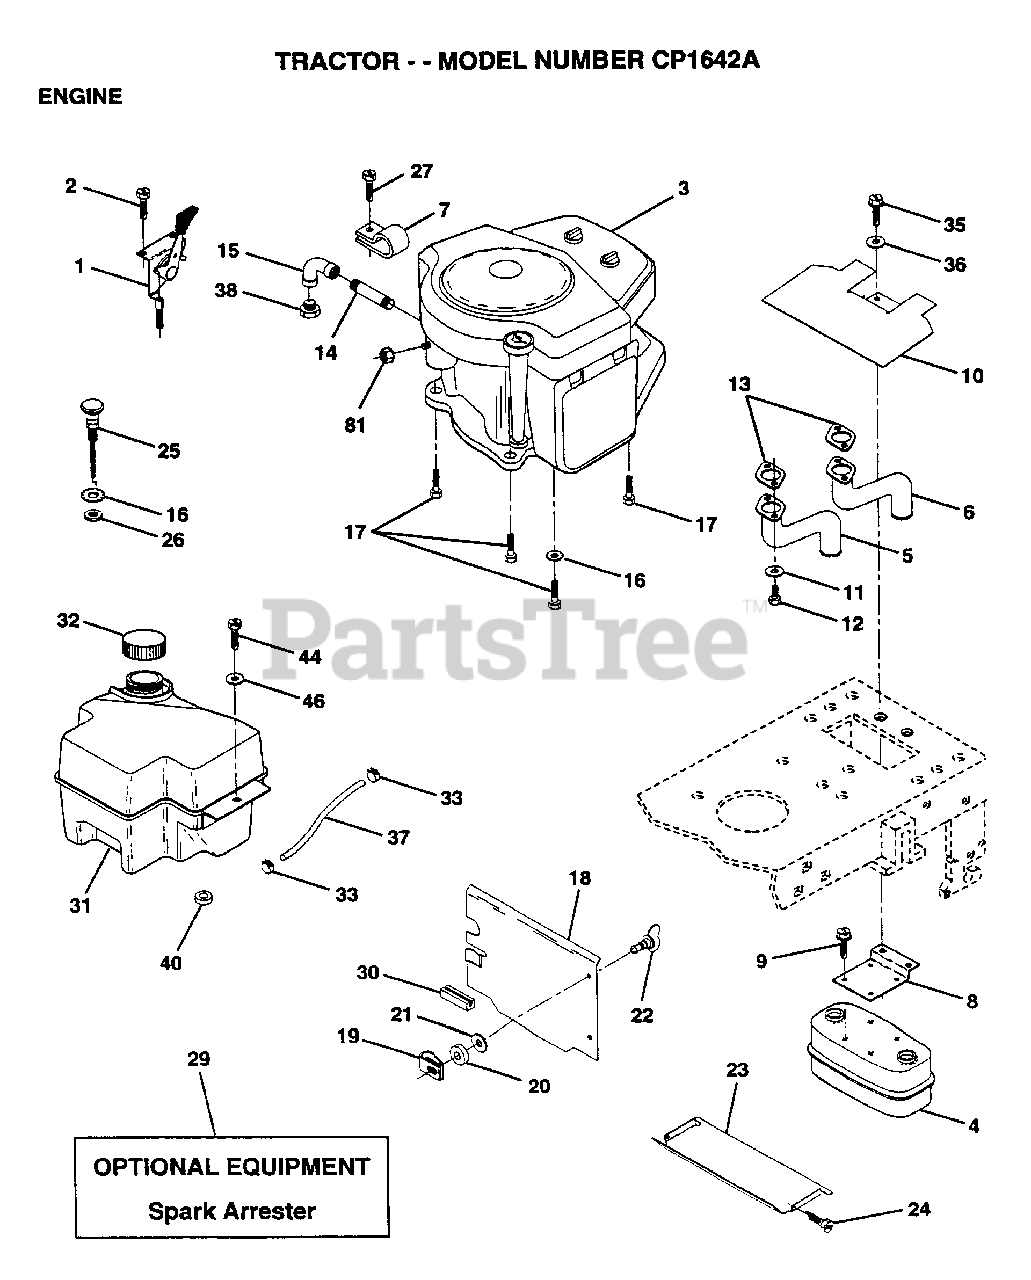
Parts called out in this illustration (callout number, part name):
1	CONTROL THRT 35.5
2	SCREW LT
3	ENGINE, B&S
5	EXHAUST.B&S.18.LH
6	EXHAUST.B&S.18.RH
7	CLAMP.TUBE.DBL.EN
8	BRACKET MUFFLER
9	SCREW ST
10	SHIELD.HEAT.
11	LOCKWASHER
14	PIPE NIPPLE LT
15	ELBOW
16	LOCKWASHER
17	SCREW LT
18	SHIELD HEAT
19	RECEPTACLE LT
20	RETAINER LT
21	WASHER
22	STUD.1/4.TURN
24	SCREW
25	CONTROL CHOKE
27	SCREW.10-24X1/2
32	CAP ASM FUEL
33	HOSE CLAMP
35	SCREW
36	WASHER
37	LINE FUEL
44	SCREW HEX CRT
46	WASHER
81	NUT
